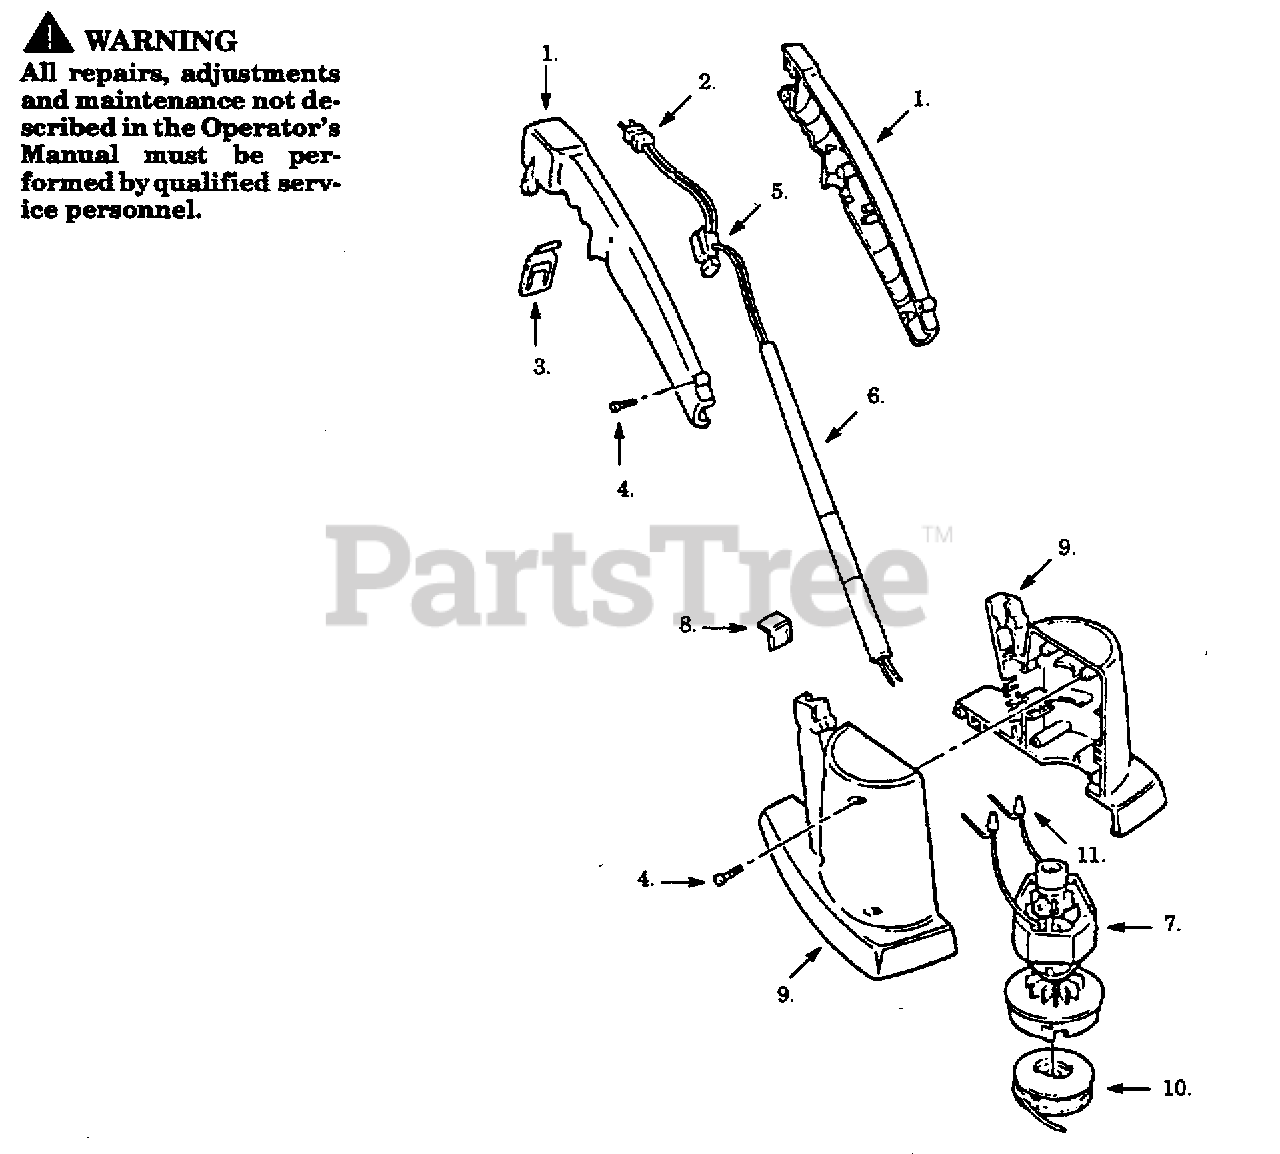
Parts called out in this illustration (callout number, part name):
1	Handle Set
2	Harness Ass'y.
3	Cord Retainer
6	Tube Assy.
7	Motor & Head Ass'y.
8	Line Cutter
9	Housing Set
10	Spool & Line
11	Terminal Cap
